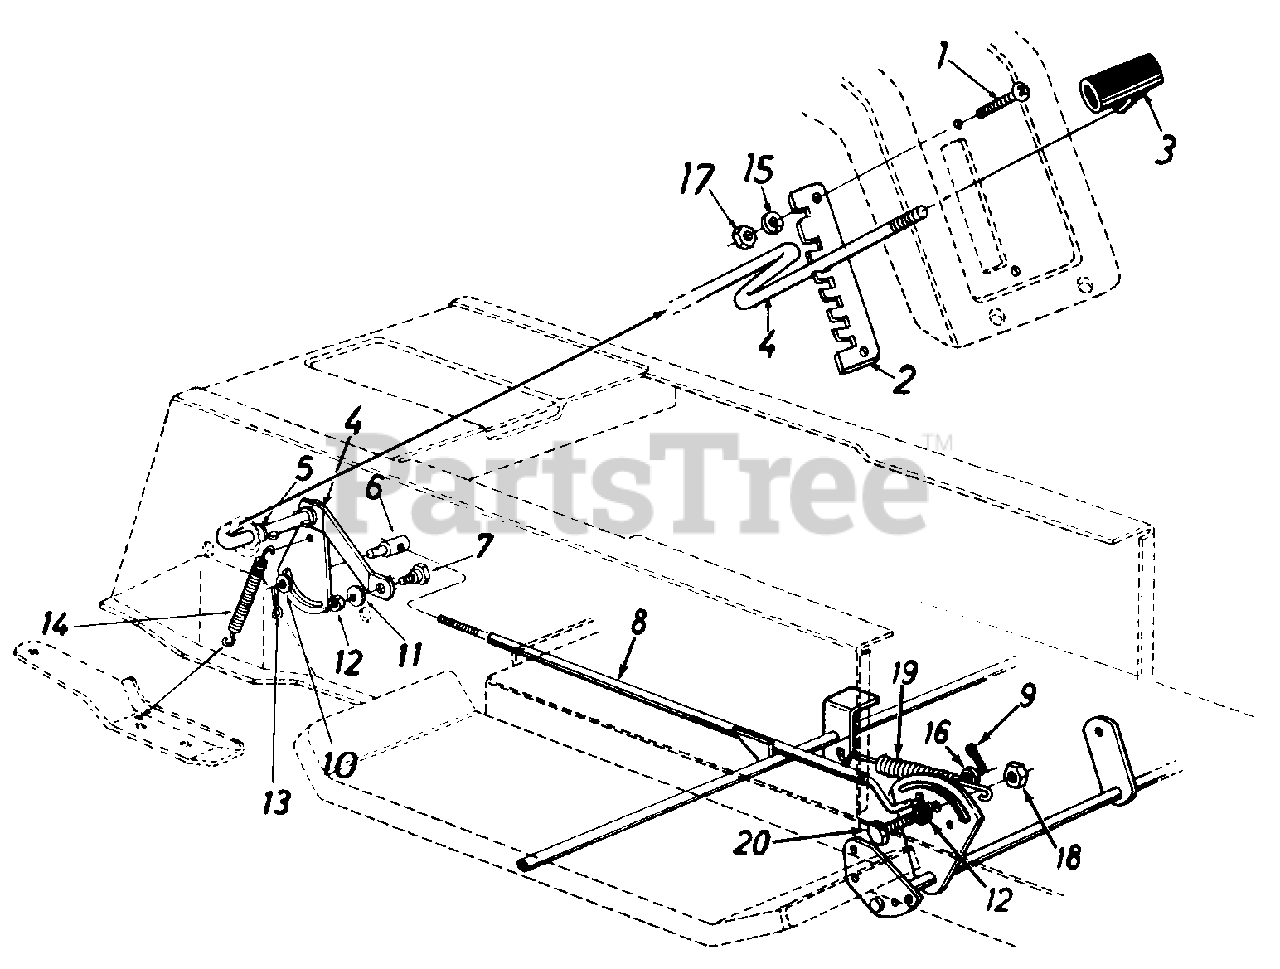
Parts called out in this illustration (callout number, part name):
1	Truss Mach . Scr. 1/4-20 x .62" Lg.
2	Speed Selector Plate
3	Shift Knob
4	Speed Selector Cam Ass'y.
5	Flat Washer .53" I.D. x .93"
6	Ferrule 3/8-24 x .37" Dia.
7	Shoulder Bolt .435" Dia. x .160
8	Speed Control Rod Ass'y.
9	Cotter Pin 3/32" Dia. x .75"
10	Fl-Wash. .385" I.D. x .62" O.D.
11	L-Wash. 5/16" I.D.
12	Hex Nut 5/16-18 Thd.
13	Cotter Pin 3/32 Dia. x .75"
14	Spring
15	L-Wash. 1/4" I.D.
16	Fl-Wash. .47" I.D. x .88" O.D.
17	Hex Nut 1/4-20 Thd.
18	Hex Cent L-nut 5/16-18 Thd.
19	Ext. Spring 4.75" Lg.
20	Hex Bolt 5/16-18 x 1" Lg.
